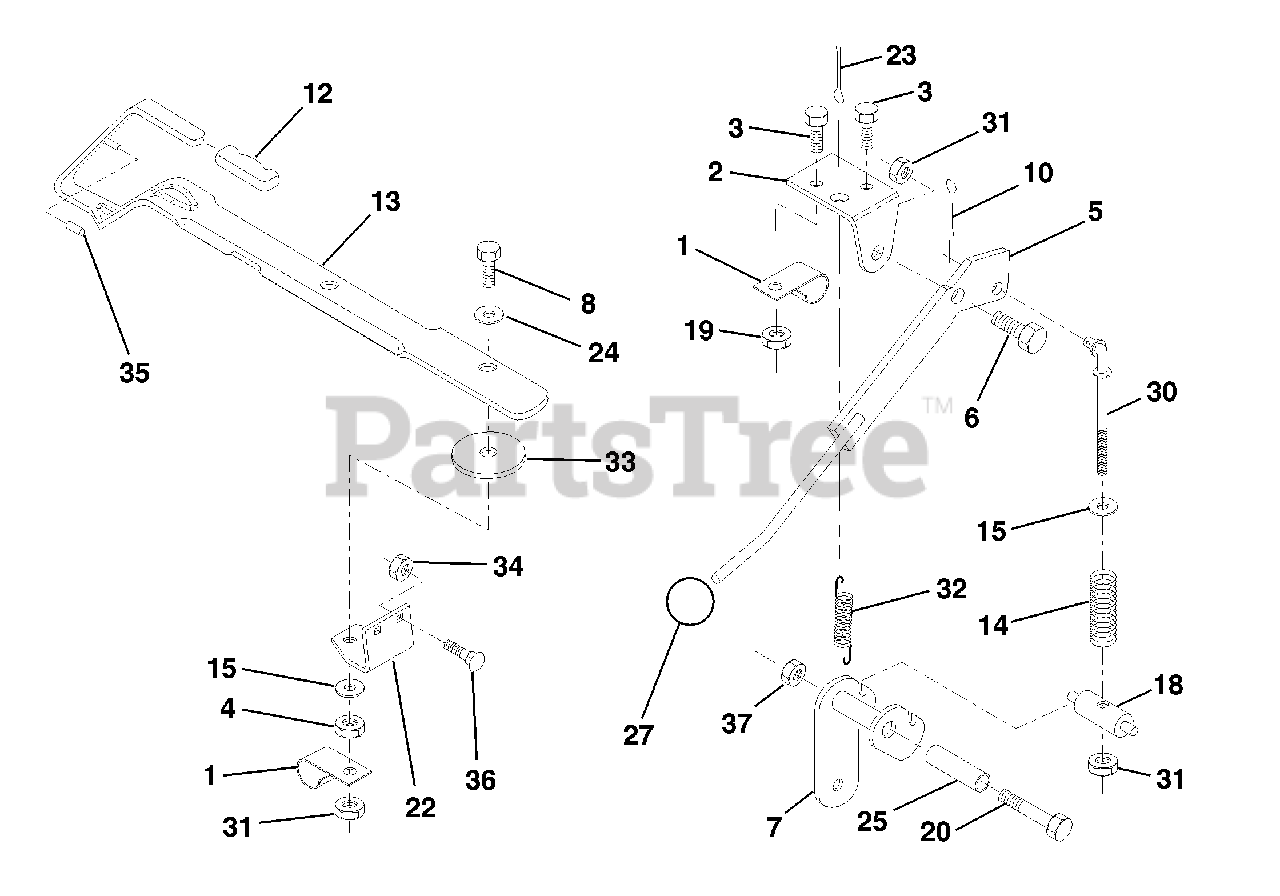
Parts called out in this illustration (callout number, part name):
1	Clip, Insulated
2	Bracket, Mower Clutch
3	Bolt, Blk Fin. Hex 1/4-20 x 1/2
4	Nut,Lock Hex w/Wsh 3/8-16
5	Assembly, Clutch Lever
6	Bolt, Shoulder
7	Assembly, Mower Clutch Arm
8	Bolt, Hex Head 3/8-16 UNC x 1-1/2
10	Pin, Cotter 1/8 x 3/4
12	Handle, Lift Lever
13	Assembly, Lift Handle
14	Spring, Compression
15	Washer 13/32 x 1 x 11 Gauge
18	Trunnion, Threaded 3/8-16
19	Nut, Crownlock 1/4-20
20	Bolt, Hex Hd Fin 3/8-16 UNC x 2-3/4
22	Bracket, Lift Lever
23	Pin, Cotter 3/32 x 3/4
24	Washer 25/64 x 1-1/4 x 12 Gauge
25	Tube, Spacer
30	Rod, Tension, Clutch
31	Nut, Lock Hex W/Ins. 3/8-16
32	Spring, Extension, Return
33	Washer .390 x 1.437 x .074
34	Nut,Lock Hex w/Ins 5/16-18
35	Cap, Vinyl, Red
36	Bolt, Carriage 5/16-18 x 3/4
37	Nut, Crownlock 3/8-16
